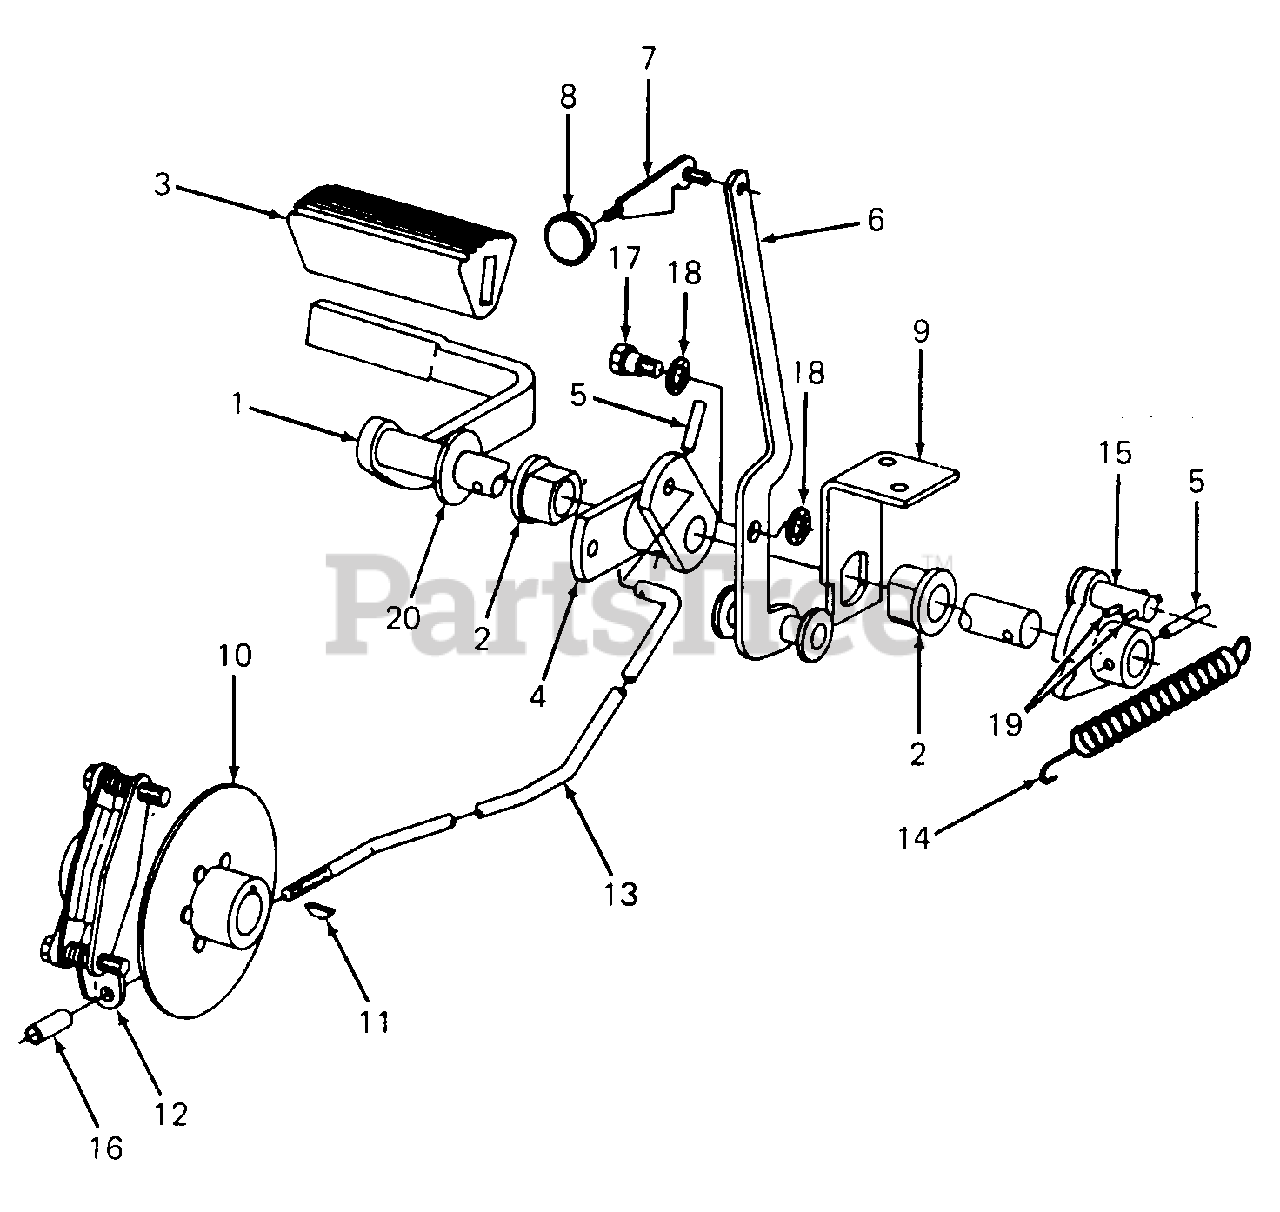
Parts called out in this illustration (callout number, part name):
1	Pedal, Brake
2	Bearing, Flanged
3	Pad, Foot
4	Control, Brake Link
5	Pin, 1/4 X 1-1/4 Pln Slt-Spr
6	Lever, Parking Brake
7	Handle, Brake Lock
8	Knob, Brake Lock Handle
9	Bracket, Brake
10	Disc & Hub
11	Key, No. 9 Hi-Pro
12	Brake Assy, Caliper For Components See Brake Assembly
13	Rod, Brake
14	Spring, Brake Pedal Return
15	Cam, Hydro
16	Spacer, .375 X .50 X 1.42
17	Screw, Shoulder
18	Washer, Wave
19	Pin, 5/32 X 3/4 Slt-Spg
20	Washer, .781 X 1.25 X .054
